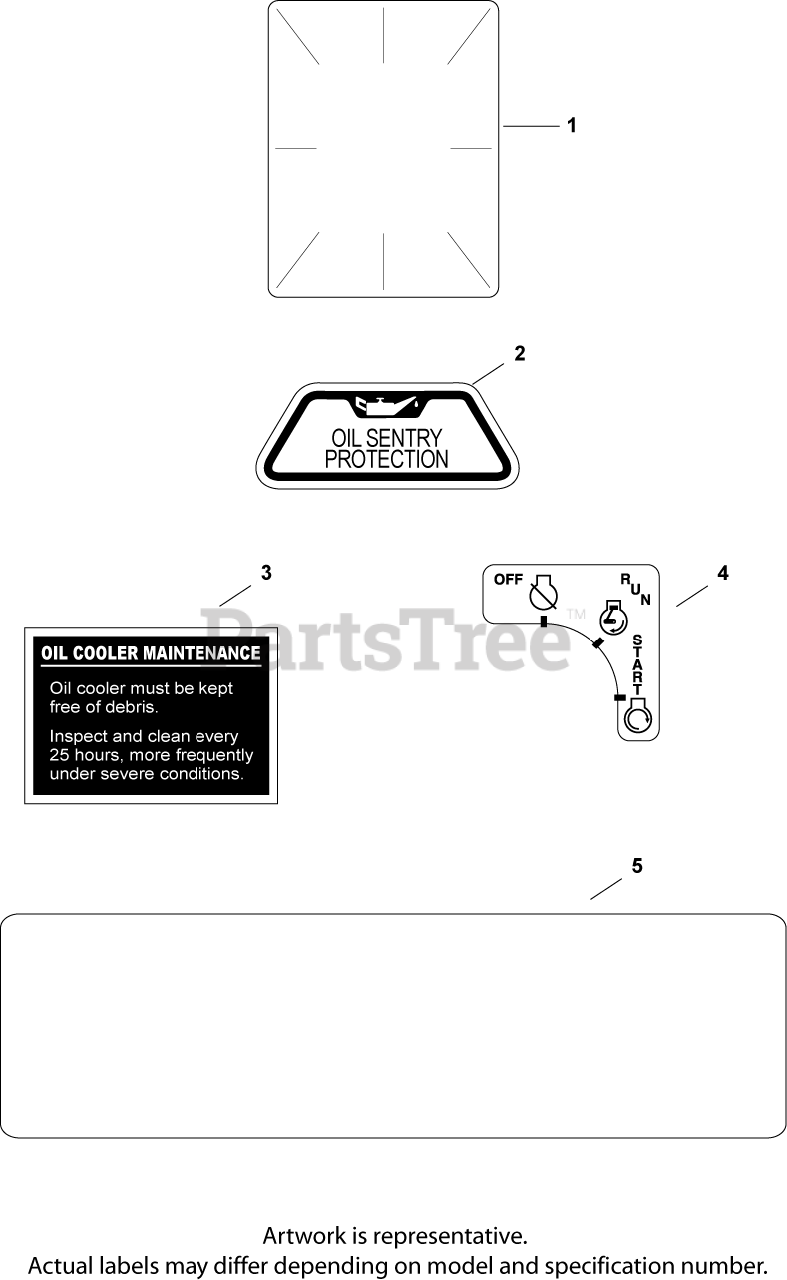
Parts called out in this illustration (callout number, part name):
1	DECAL, CLEAR LAMINATE USE 25 113 70-S
2	DECAL, OIL SENTRY - (#DSC)
3	DECAL, OIL COOLER - (#DSC)
4	DECAL, KEY SWITCH
5	DECAL, 25 HP
